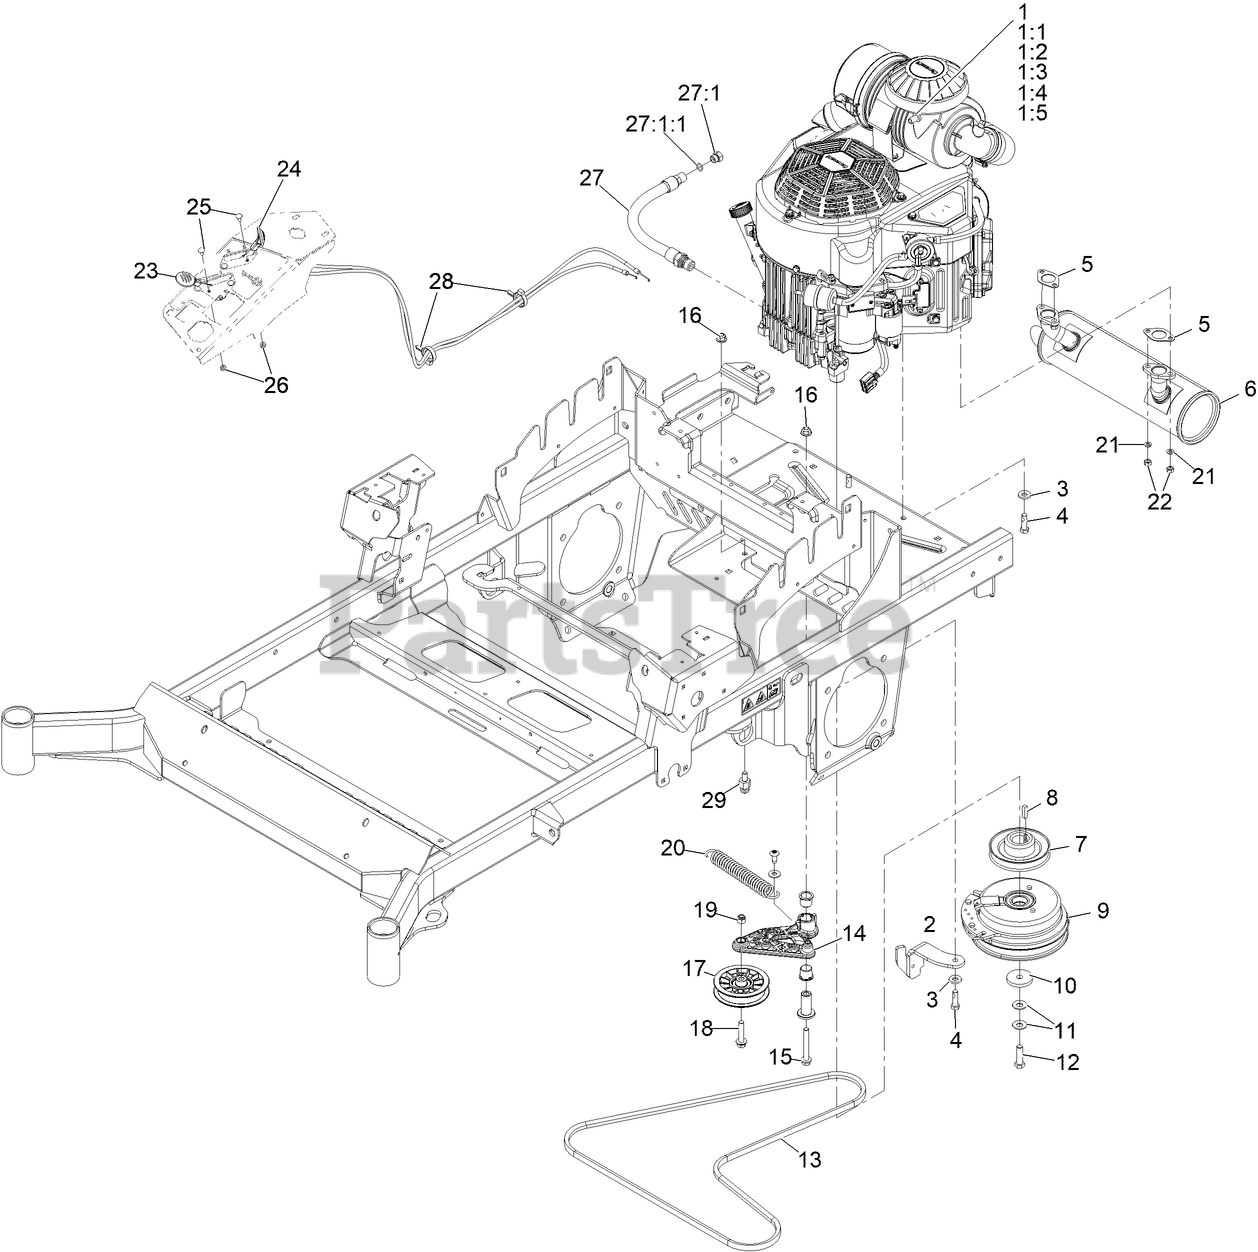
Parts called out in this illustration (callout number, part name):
1:5	SPARK PLUG
2	Bracket, Clutch Anchor
3	WASHER-BELLEVILLE
4	Screw-HH, Patch
5	GASKET-EXHAUST
6	MUFFLER, KAWASAKI
7	Sheave, Engine
9	Clutch, Cms-175
10	WASHER-CLUTCH
11	WASHER-SPRING
12	SCREW-HH 7/16-20 X 1 1/2 W/LOCTITE
13	Belt, A-Section
14	ASM, Idler Arm W/ Bushings
15	SCREW-HFH
16	NUT-HF, NI
17	PULLEY-FLAT IDLER
18	SCREW-HHF
19	NUT-LOCK, NI
20	Spring, Extension
21	WASHER-LOCK
23	CABLE-CONTROL, THROTTLE
24	CABLE-CONTROL, CHOKE
25	BOLT-CARR
26	NUT-LOCK, NI
27	ENGINE OIL DRAIN HOSE ASM
27:1	PLUG-HH
27:1:1	O-RING
28	CLAMP-HOSE
29	PIN, SPRING ANCHOR
